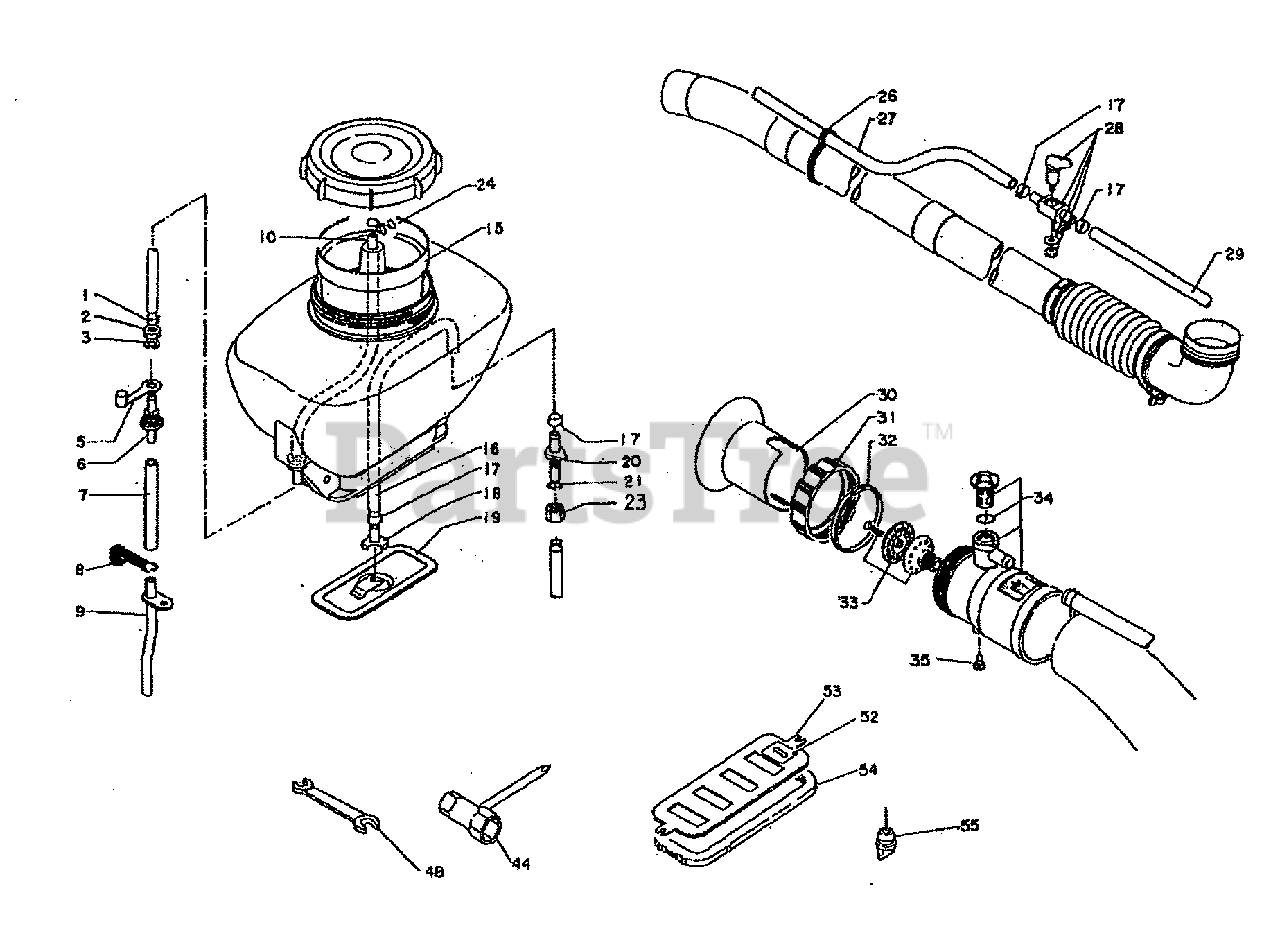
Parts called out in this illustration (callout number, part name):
1	Clamp
3	Washer
6	Connector
9	Tube
15	Filter, Tank
16	Tube
17	Clamp
18	Mouth, Suction
19	Plate
20	Connector
24	Clip
26	Clip
28	Valve
34	Head, Nozzle
35	Screw, Nozzle
44	Wrench 13x19
53	Shutter Ass'y
